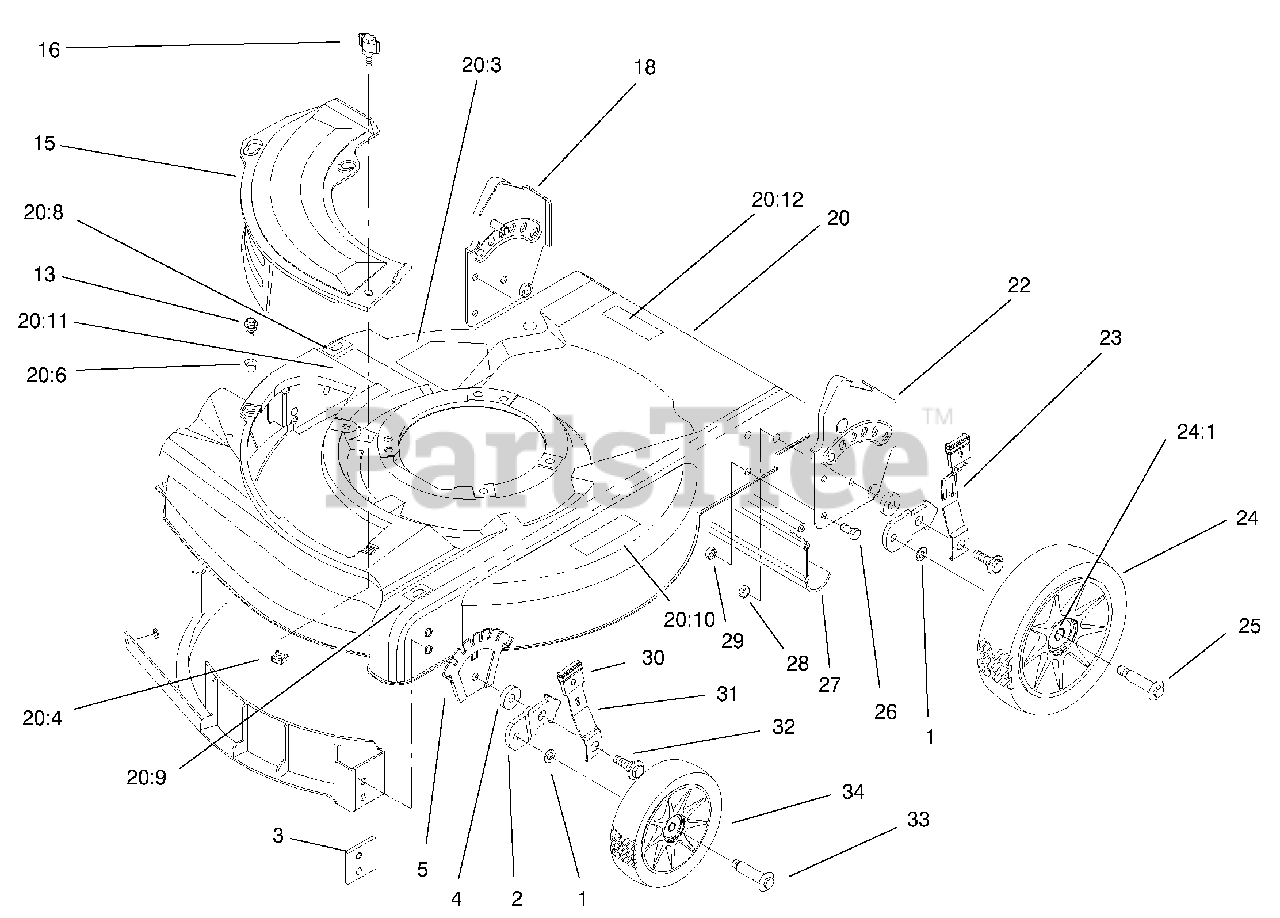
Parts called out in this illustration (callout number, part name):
2	BRACKET-HEIGHT ADJUSTMENT, WHEEL
3	PLATE - BAFFLE
4	WASHER-WHEEL
5	PLATE - HEIGHT ADJUSTMENT
13	SCREW-SEMS
15	PLATE-MULCH
18	RH HANDLE BRKT ASM
20	HOUSING-SERVICE
20:3	DANGER DECAL(FR/E)
20:4	NUT-CAGE
20:6	GROMMET - PLASTIC
20:8	DECAL-HOC,RH
20:9	DECAL-HOC,LH
20:10	DECAL-WARNING
20:11	DECAL-WARNING
20:12	DECAL-MANUAL,LB
22	LH HANDLE BRKT ASM
23	SPRING ARM ASM - REAR
24	8" WHEEL & TIRE ASM
25	BOLT-SHOULDER
26	SCREW-HH
27	SHIELD - TRAILING
28	NUT-LOCK, NI
29	NUT-LOCK, NI
30	KNOB-LEVER, HEIGHT ADJUSTMENT
31	ARM-FRONT SPRING
32	BOLT-SHOULDER
33	BOLT-SHOULDER
34	WHEEL & TIRE ASM
